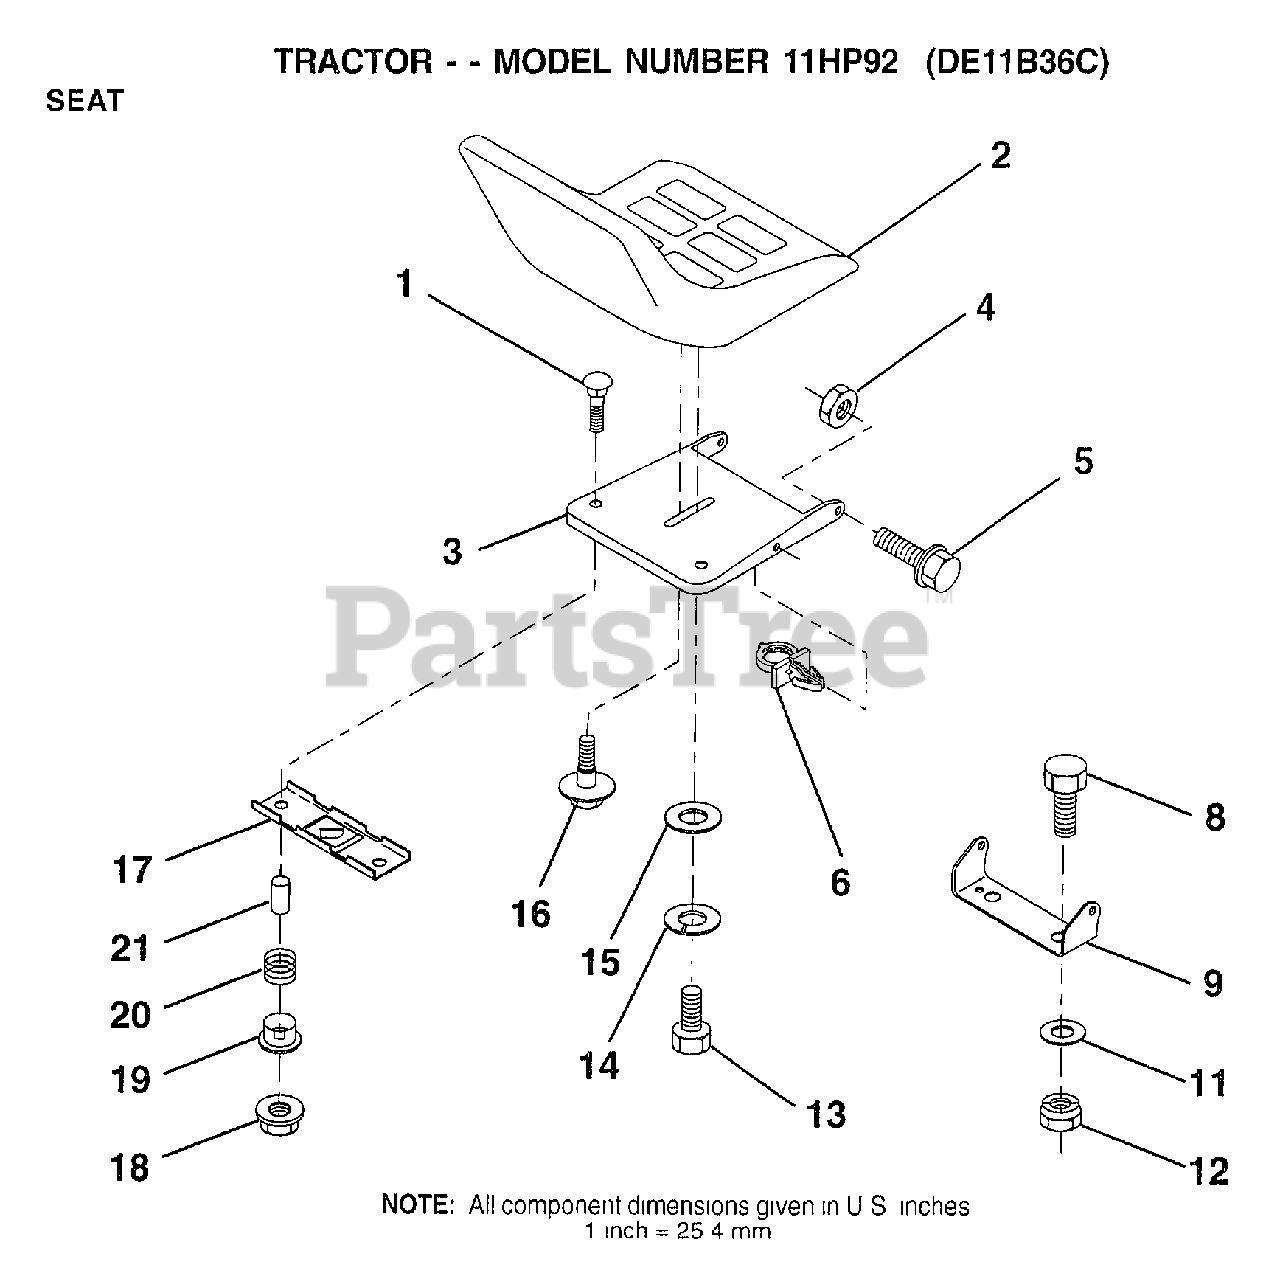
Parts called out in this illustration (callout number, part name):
1	BOLT-RD HD SQ NK
3	PAN-SEAT
4	NUT
5	BOLT
6	CLIP.PUSH-IN.HING
8	BOLT
9	BRACKET PVT SEAT
11	WASHER
12	NUT
13	BOLT
14	LOCKWASHER
15	WASHER
16	"BOLT,SHOULDER"
17	BRKT SWITCH
19	BUSHING
20	SPRING
21	SPLIT SPACER
